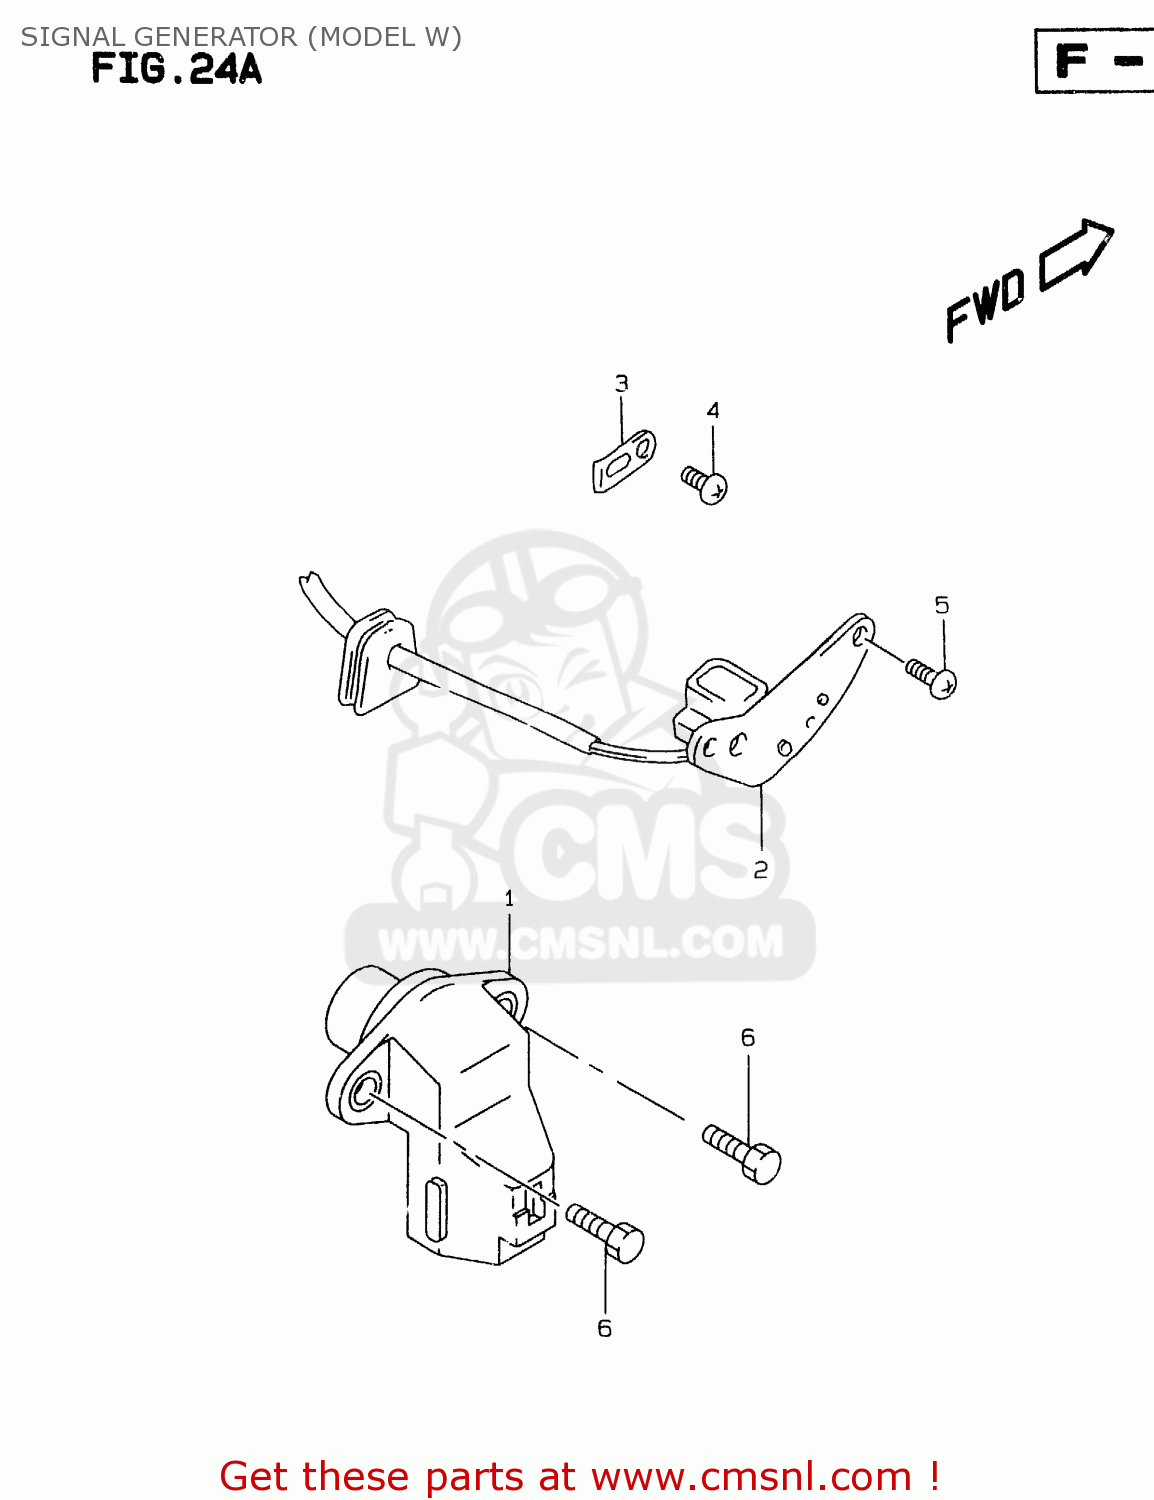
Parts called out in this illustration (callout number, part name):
1	SENSOR ASSY,CAM POSITION
2	STARTER,SIGNAL GENERATOR
3	CLAMP,SIGNAL GENERATORERATOR
4	SCREW
5	SCREW
6	BOLT,OIL FILLE
